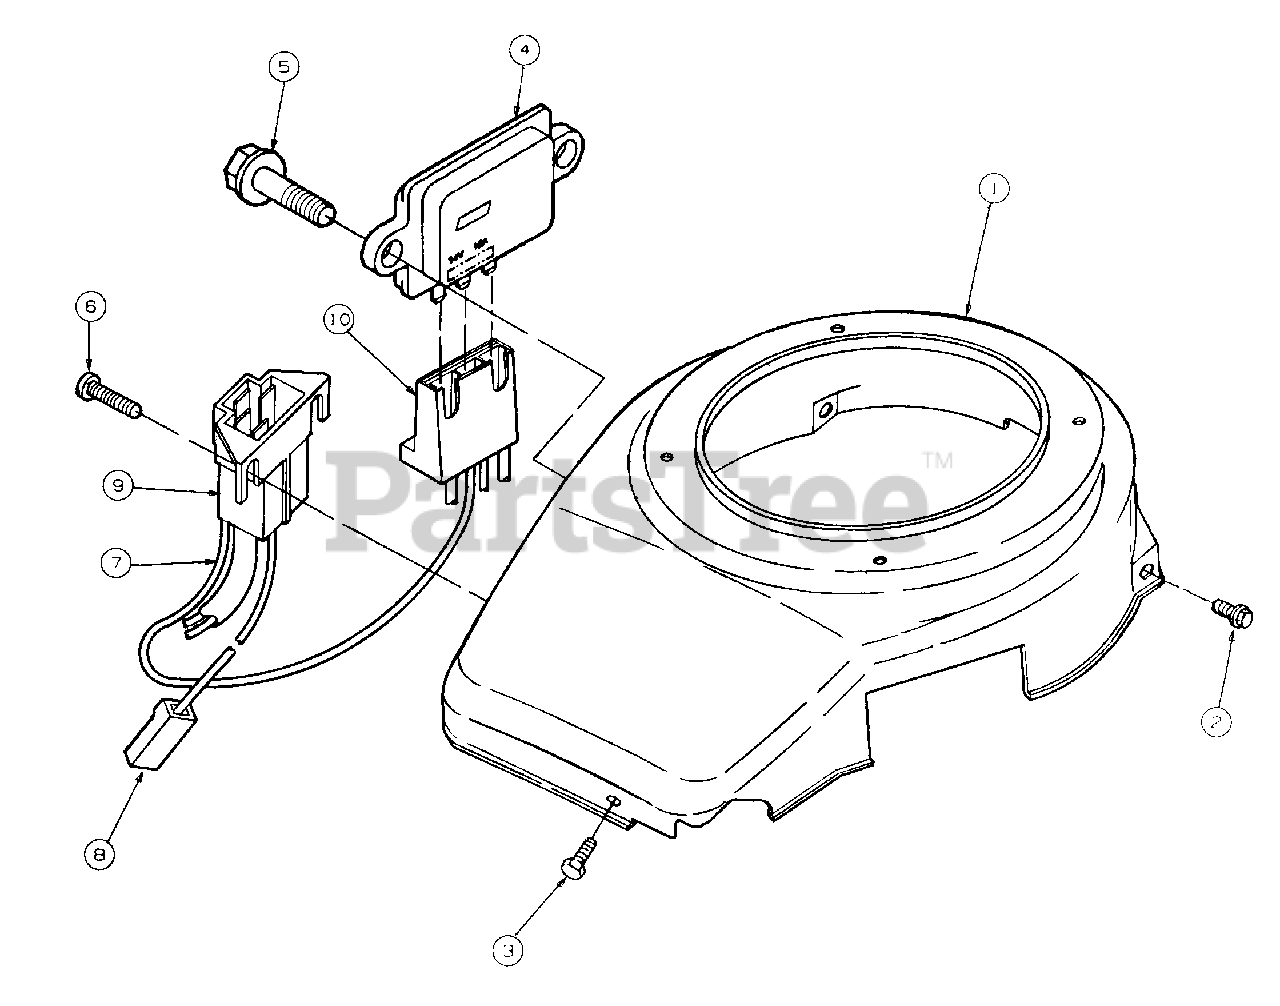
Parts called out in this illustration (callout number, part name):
1	Housing, Blower
2	Screw, Hex Washer Head Locking, M6 x 1 x 16 mm
3	Bolt, Hex Head Cap
4	Regulator, Voltage
5	Screw, Hex Washer Head, Sheet Metal, 1/4-14 x 1/2
6	Screw, Pan Head Torx, M4 x .7 x 12 mm
7	Harness, Engine Wiring
8	Housing, Receptacle
10	Body, Connector
